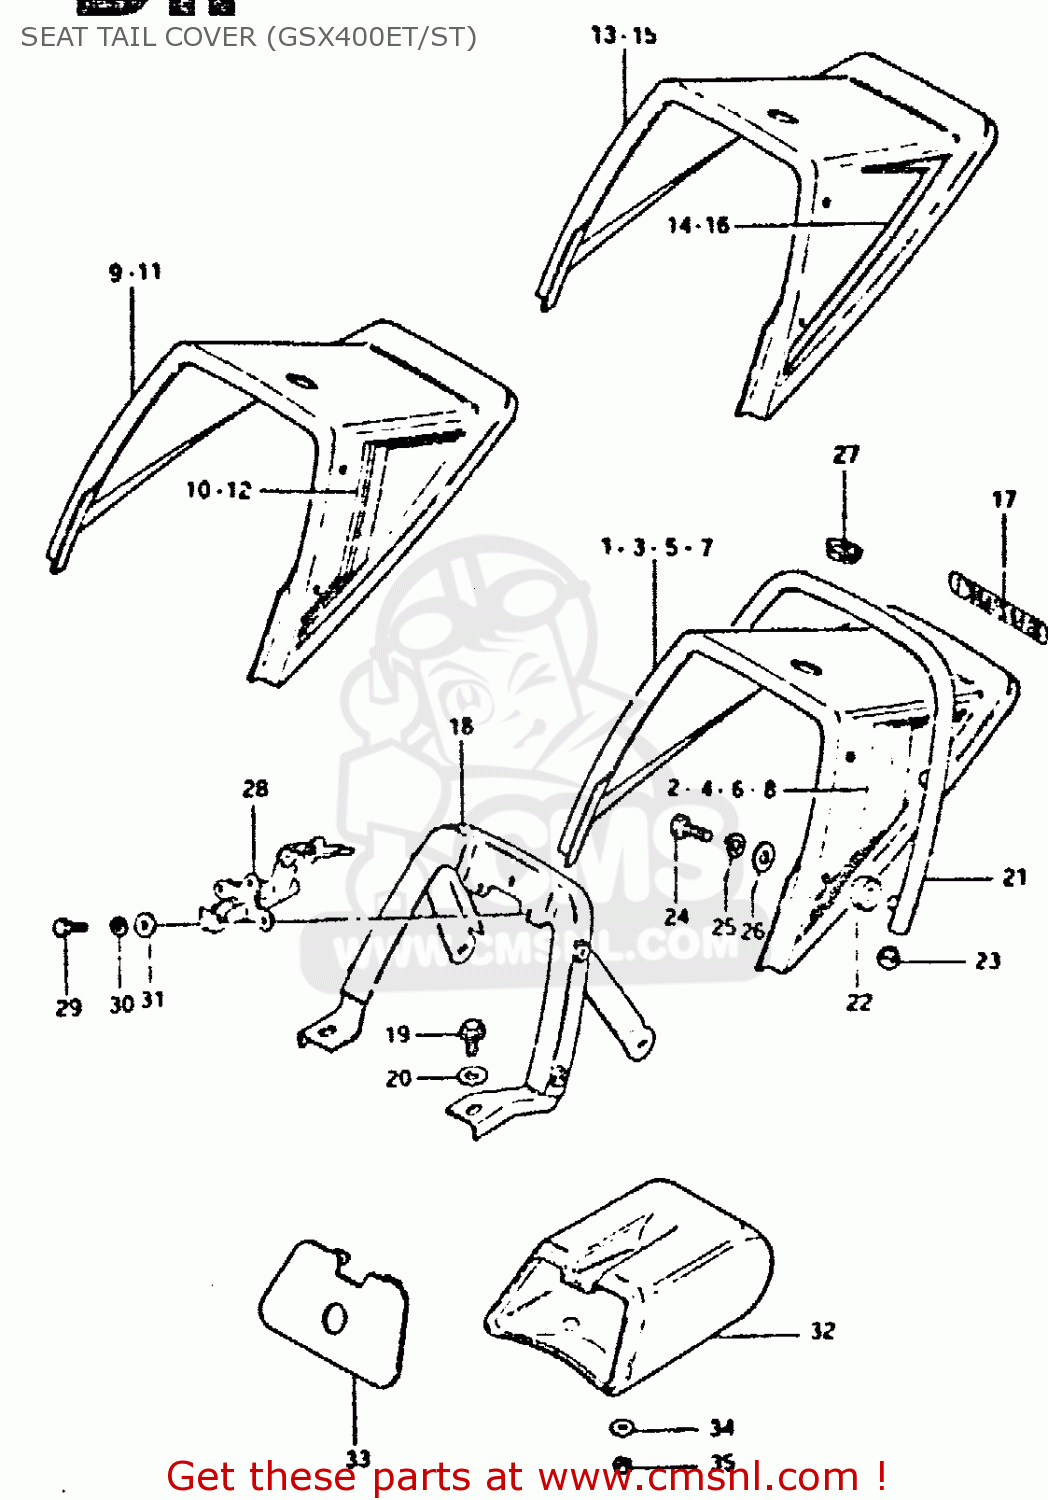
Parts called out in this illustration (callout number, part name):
1	COVER,SEAT TAIL
2	TAPE SET
3	TAIL COVER, SEAT (BLUE)
4	TAPE SET
5	COVER,SEAT TAIL
6	TAPE SET
7	COVER,SEAT TAIL
8	TAPE SET
9	COVER,SEAT TAIL
10	TAPE SET
11	COVER,SEAT TAIL
12	TAPE SET
17	EMBLEM,SEAT TAIL COVER
18	BRACKET, SEAT TAIL COVER
19	BOLT
20	WASHER (8.7X22X2)
21	HANDLE,PILLION RIDER
22	CUSHION
23	END,SHEET HANDLE
24	BOLT (8X30)
25	LOCK WASHER
26	WASHER
27	GROMMET,SEAT LOCK HOLE
28	LOCK SET
29	BOLT
30	LOCK WASHER
31	WASHER
32	BOX, SEAT TAIL
33	LID,SEAT TAIL BOX
34	WASHER
35	NUT 6MM
